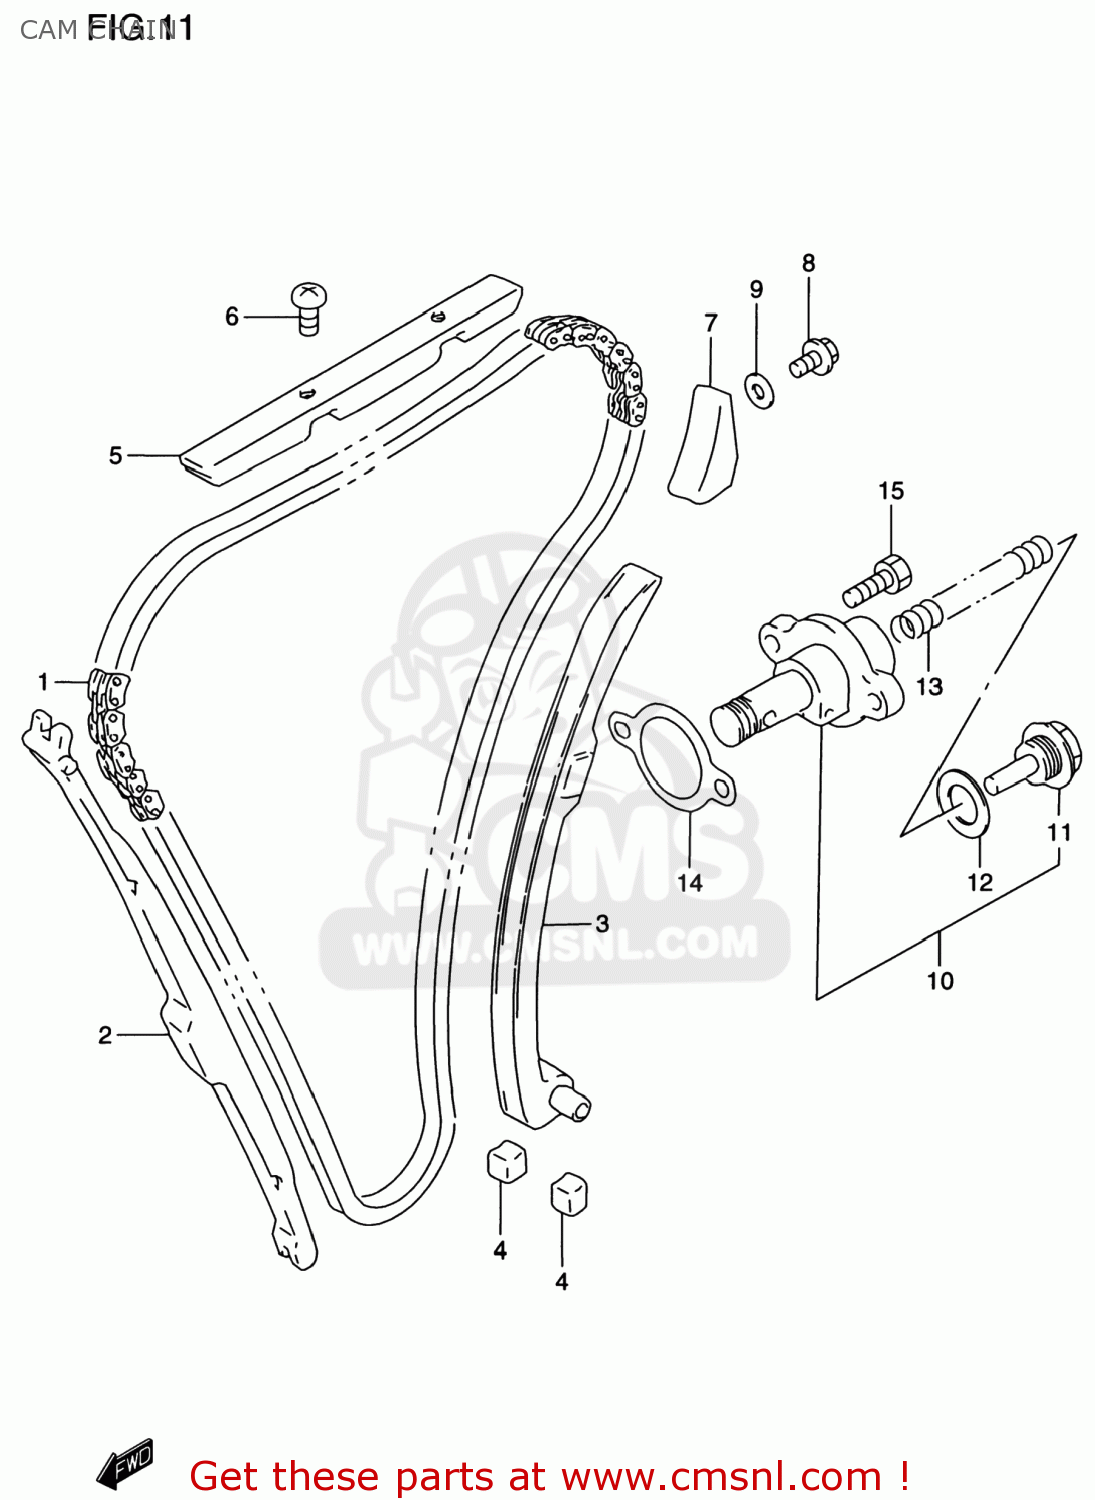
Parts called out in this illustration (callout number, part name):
1	CHAIN,CAMSHAFT DRIVE
2	GUIDE,CAM CHAIN NO.1
3	TENSIONER,CAM CHAIN
4	CUSHION,CAM CHAIN TENSIONER
5	GUIDE,RR CAM CHAIN NO.1
6	SCREW
7	GUIDE,CAM CHAIN NO.2
8	BOLT
9	GASKET(5.8X13X1.2) (NAS)
10	ADJUSTER ASSY,TENSIONER
11	PLUG
12	GASKET (NAS)
13	SPRING
14	GASKET,TENSIONER ADJUSTER (NAS)
15	BOLT,CL.COVER
